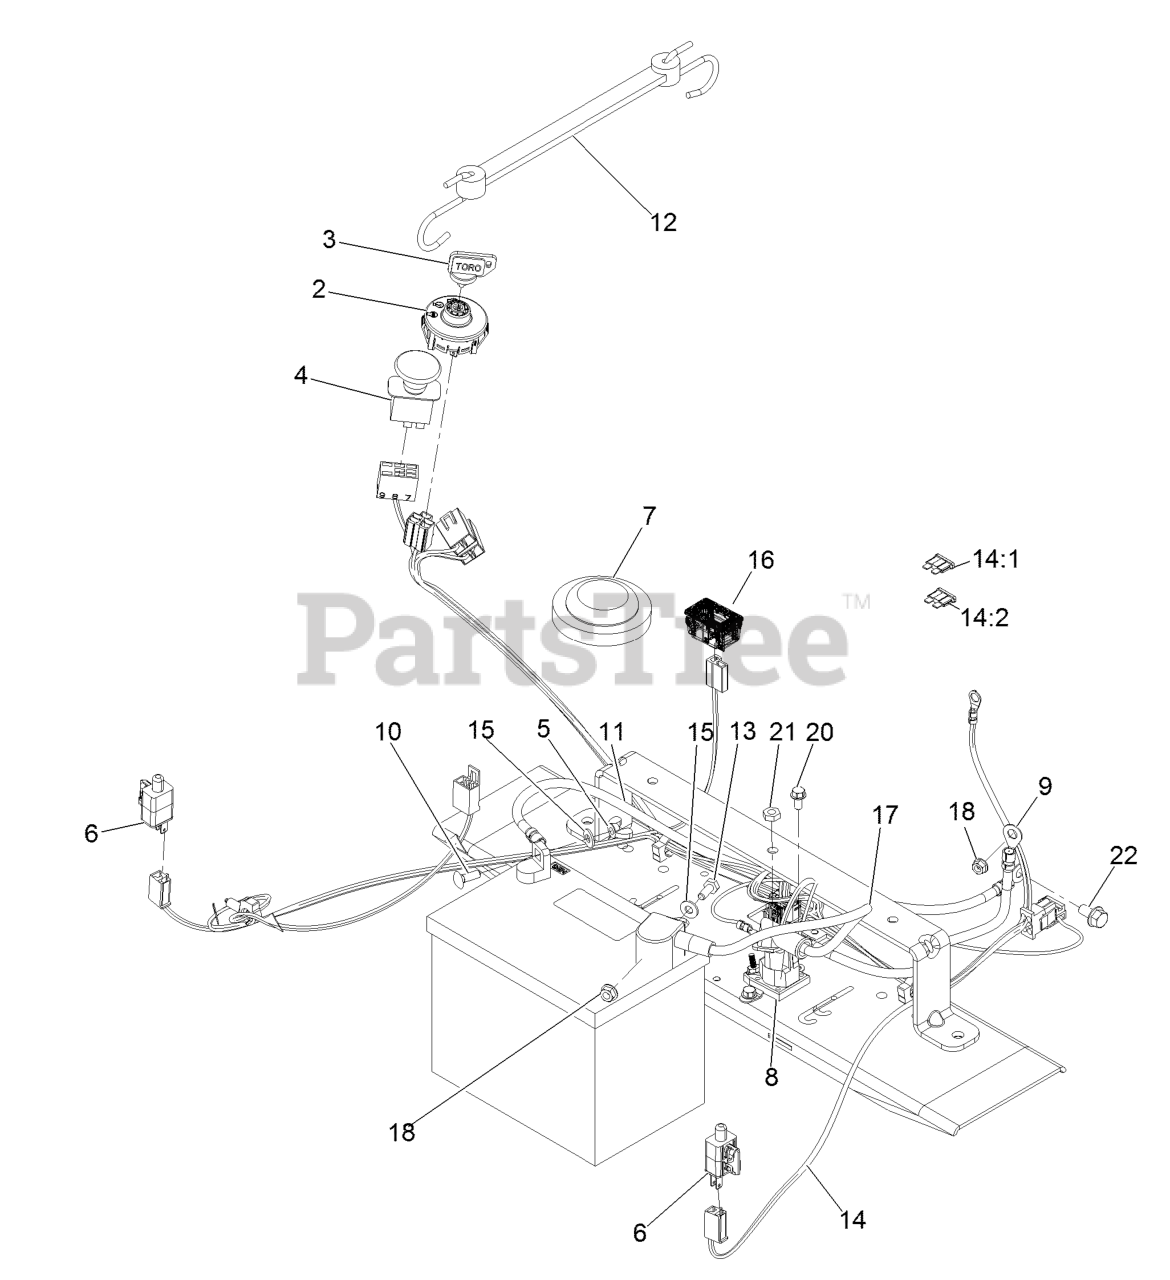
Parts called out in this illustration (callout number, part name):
3	KEY-IGNITION
4	SWITCH-PTO
5	NUT-WING
7	SWITCH-SEAT
8	SOLENOID
9	CABLE-BATTERY, RED
10	BOLT-CARR
11	CABLE-BATTERY, BLACK
12	HOLDDOWN-BATTERY
13	SCREW-HH
14:1	FUSE-BLADE, 30 AMP
14:2	FUSE-BLADE, 25 AMP
15	WASHER-FLAT
16	HOURMETER
17	CABLE-BATTERY, RED
20	SCREW-HWH
21	NUT-JAM
22	SCREW-HHF
